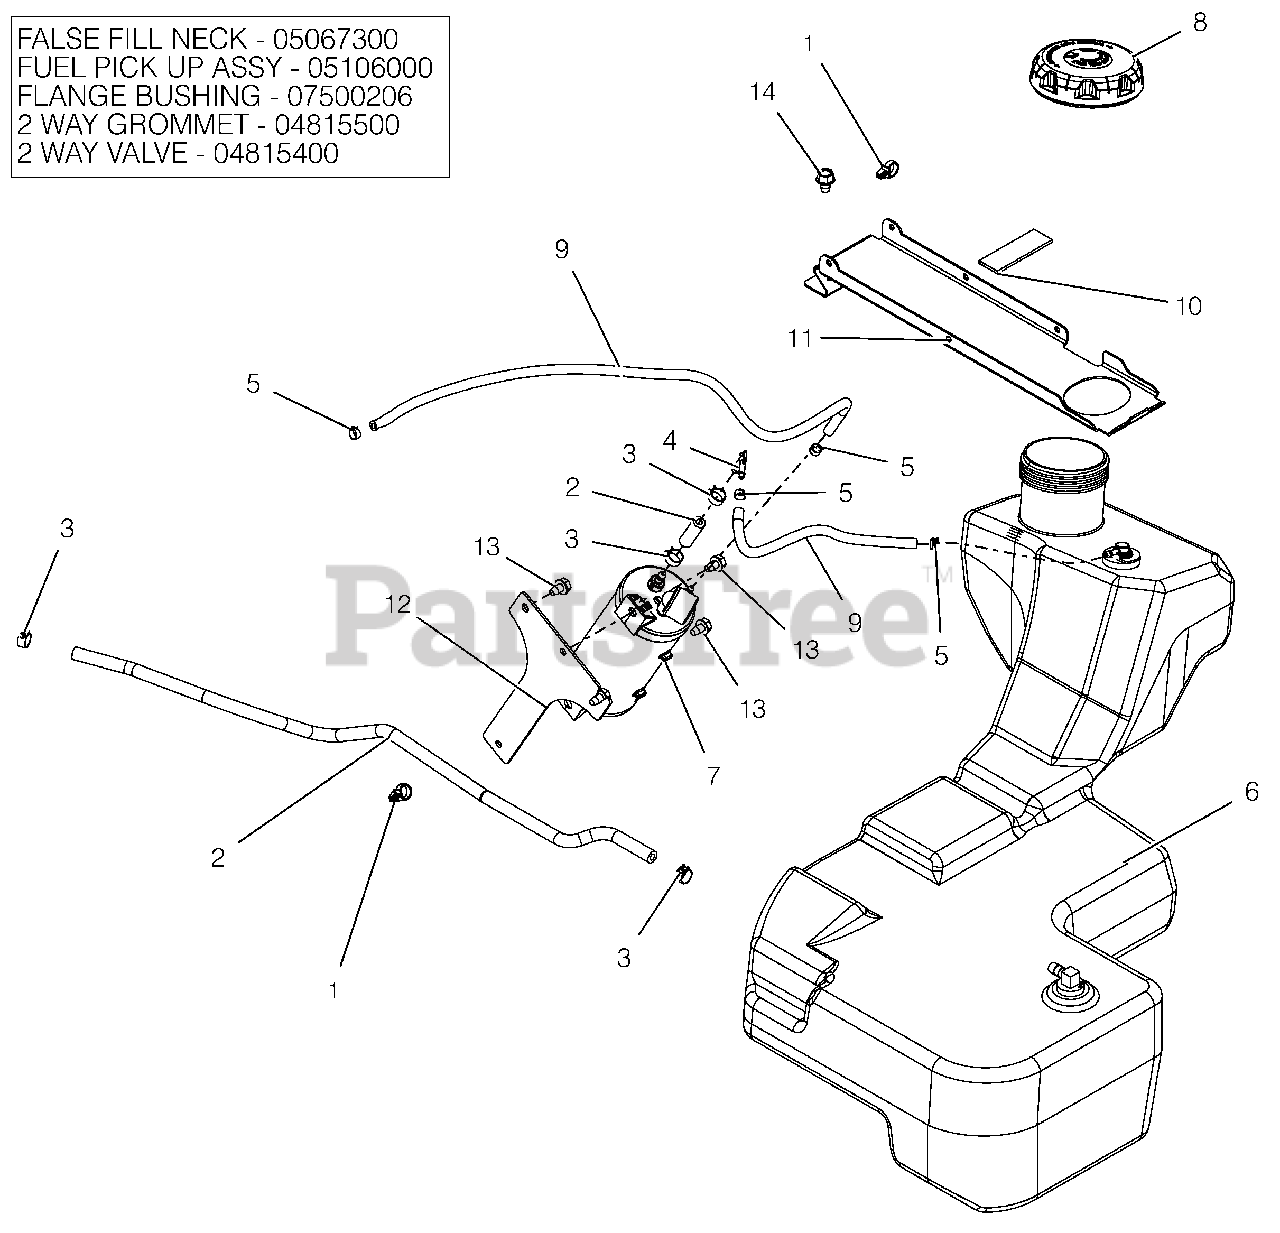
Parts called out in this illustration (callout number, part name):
1	ROUTING CLIP (1/2" ID)
2	HOSE, .25 LOW-PERM BULK GAS
3	CLAMP, FUEL LINE
4	FITTING-3/16X1/4 90DEGREE VAC
5	CLAMP-HOSE, SPRING .188
6	ASM, HD FUEL TANK
6	INSERT, FUEL NECK FALSE FILL
6	ASM, HD FUEL PICK-UP
6	BSHG-FLG .375X1.062X.625 NITR
6	GROMMET, 2-WAY
6	VALVE, 2-WAY
7	CANISTER, 400 CC CARB
8	CAP, FUEL VENTIN AUTOLOCK
9	HOSE, .188 30R7 BULK
10	PAD,RBR 1.0"X3.0" W/ADHESIVE
11	BRKT, FUEL TANK HOLD DOWN
12	BRKT, CARB CANISTER MTG (HD)
13	@SCR-TAP .31-18X.50 HWH TR YWZ
14	@SCR-TAP .38-16X.50 HWH TR YWZ
